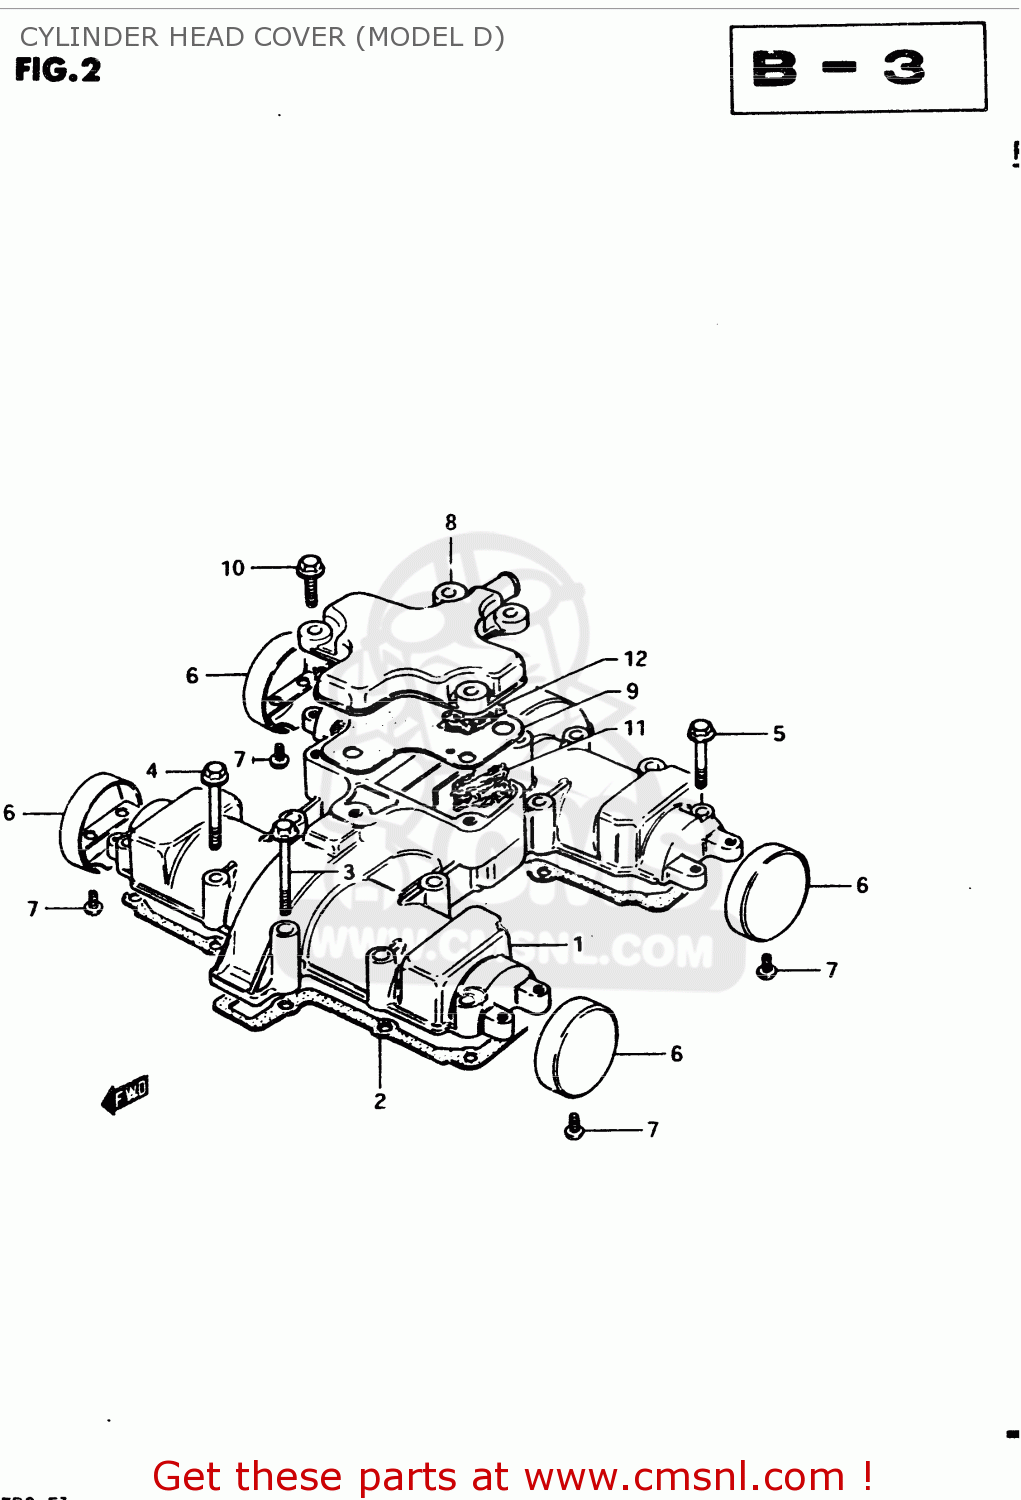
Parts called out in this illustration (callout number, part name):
1	COVER,CYLINDER HEAD
2	GASKET,CYLINDER HEAD COVER (MCA)
3	BOLT (6X45)
4	BOLT (6X40)
5	BOLT 6X30
6	CAP,CYLINDER HEAD COVER
7	SCREW
8	COVER,BREATHER
9	GASKET (MCA)
10	BOLT
11	COVER,BREATHER
12	SEPARATOR,OIL BREATHER
